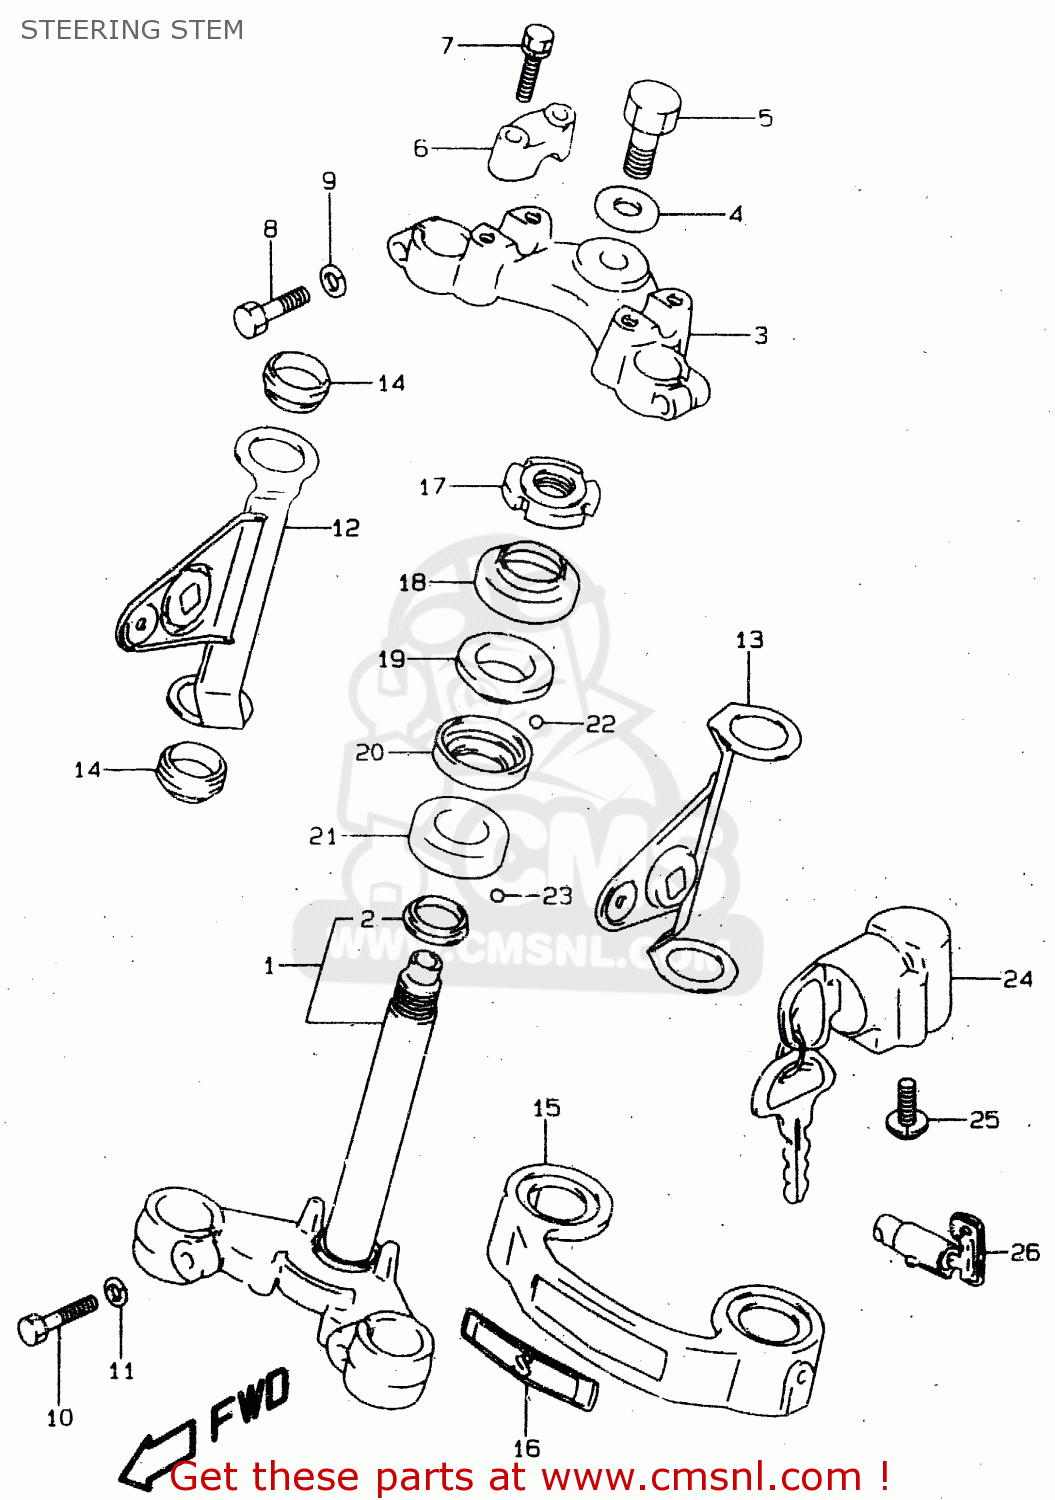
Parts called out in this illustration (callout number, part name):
1	STEM,STEERING
2	RACE,STEERING OUTER LWR
3	HEAD,STEERING STEM(BLACK)
4	WASHER,STEM HEAD(10.5X30X3.2)
5	BOLT,FR FORK(10X33)
6	HOLDER,HANDLE(BLACK)
7	BOLT
8	BOLT
9	WASHER,LOCK
10	BOLT,FR FORK LWR(12X33)
11	WASHER,LOCK
12	BRACKET,HEADLAMP,R
13	BRACKET,HEADLAMP,L
14	CUSHION,HEADLAMP BRACKET
15	COVER,FR FORK
16	EMBLEM,FR FORK COVER
17	NUT,STEERING STEM(25X44X10)
18	DUST SEAL,STEERING UPR
19	RACE,STEERING OUTER UPR
20	RACE,STEERING INNER UPR
21	LACE,STEERING INNER LWR
22	BALL
23	BALL
24	LOCK ASSY,STEERING
25	SCREW
26	LOCK ASSY,STEERING(NEIMAN)
